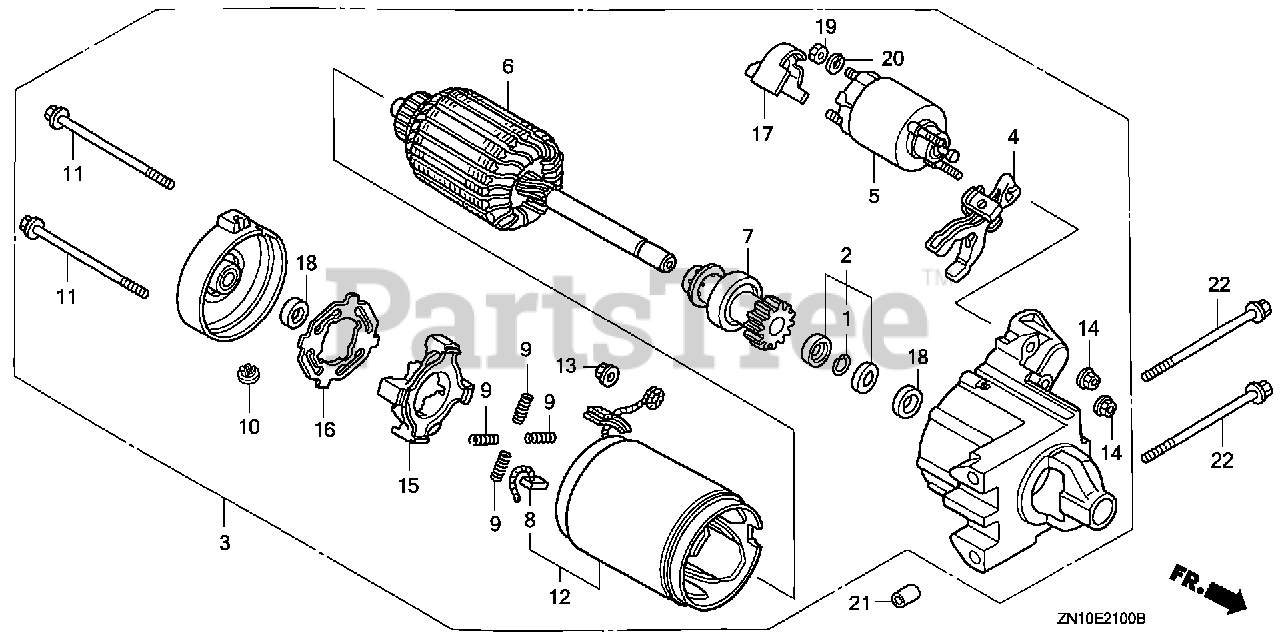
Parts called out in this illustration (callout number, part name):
1	RING, SNAP (DENSO)
2	COLLAR SET, CLUTCH STOP
3	STARTER MOTOR ASSY.
4	LEVER, PINION DRIVE
5	SWITCH ASSY., MAGNET
6	ARMATURE
7	CLUTCH COMP., OVERRUNNING
8	BRUSH
9	SPRING, BRUSH
11	BOLT, THROUGH
12	YOKE
13	NUT, HEX. (8MM)
14	NUT, FLANGE (5MM)
15	HOLDER, BRUSH
16	INSULATOR, BRUSH HOLDER
17	COVER, TERMINAL
18	BEARING A
19	NUT, HEX. (8MM)
20	WASHER, SPRING (8MM)
21	PIN, DOWEL (10X12)
22	BOLT, FLANGE (8X110)
